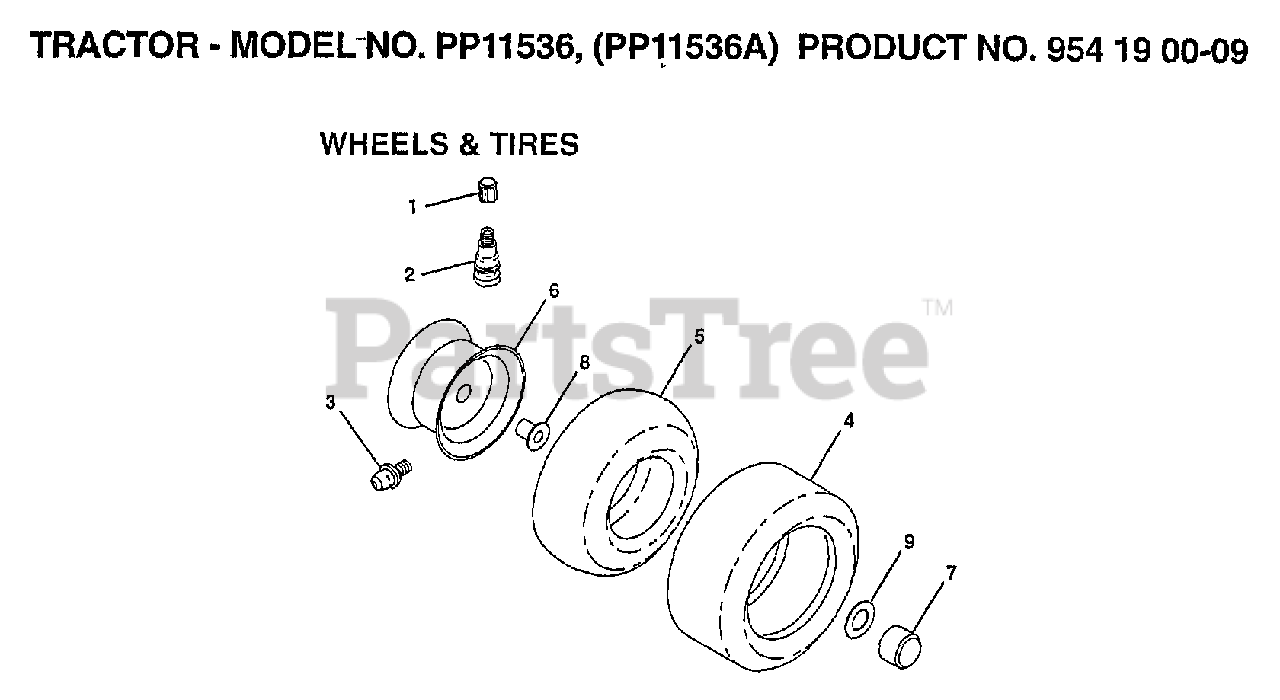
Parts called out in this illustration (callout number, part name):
1	VALVE CAP
2	VALVE STEM LT
3	FITTING LT
5	TUBE.5.3/4.5/6
6	"RIM.FRT.6"".ASM"
6	"RIM REAR 8"""
7	HUB CAP
8	"FLANGE, BEARING"
9	WASHER
